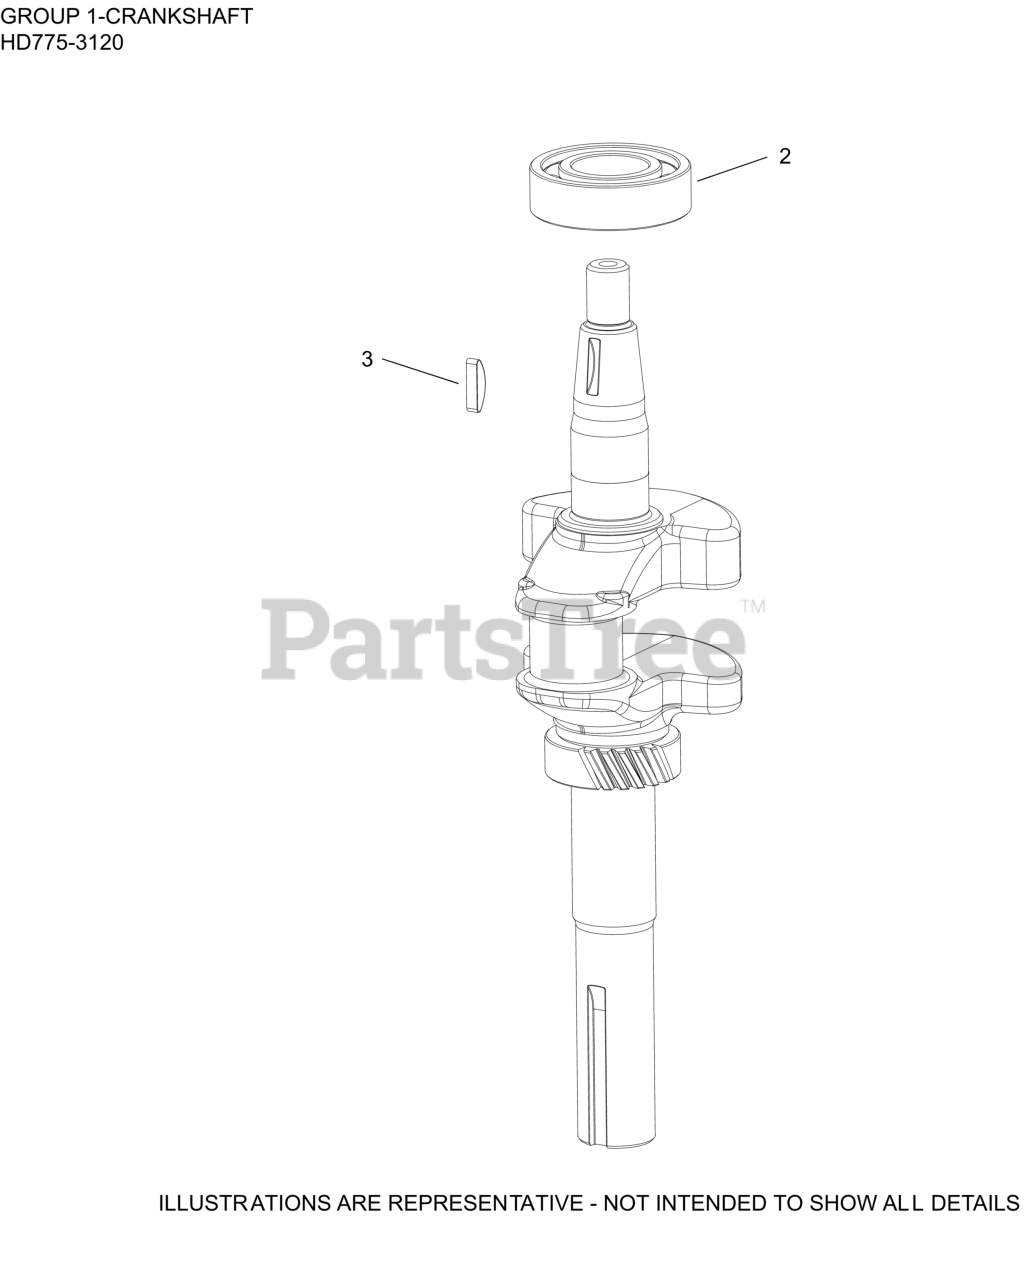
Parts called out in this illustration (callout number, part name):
2	BEARING, BALL
3	KEY, FLYWHEEL
NI	CRANKSHAFT ASSEMBLY
